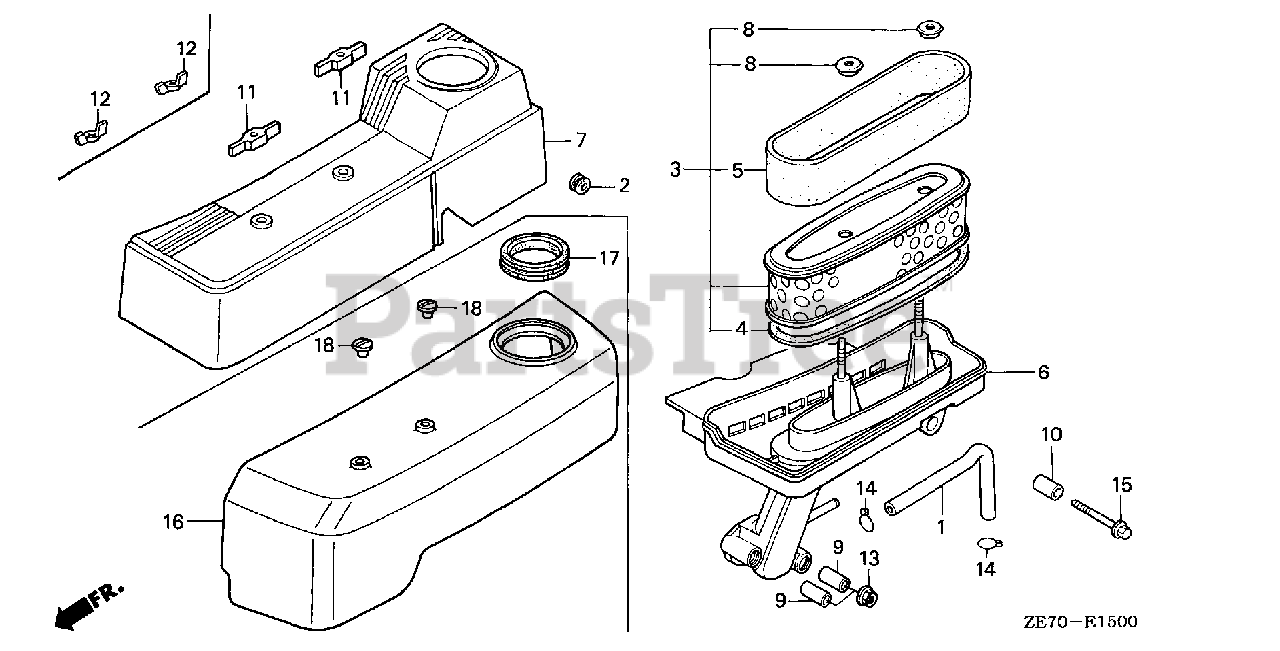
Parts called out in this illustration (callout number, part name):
1	TUBE, BREATHER
2	GROMMET, CHOKE ROD
3	ELEMENT, AIR CLEANER
4	GASKET, ELEMENT
5	FILTER (OUTER)
6	HOUSING, AIR CLEANER
7	COVER, AIR CLEANER
8	GROMMET, AIR CLEANER
9	COLLAR, AIR CLEANER
10	COLLAR B, AIR CLEANER
11	WINGNUT (6MM) (BLACK)
12	NUT, TOOL BOX SETTING
13	NUT, FLANGE (6MM)
15	BOLT, FLANGE (6X35)
